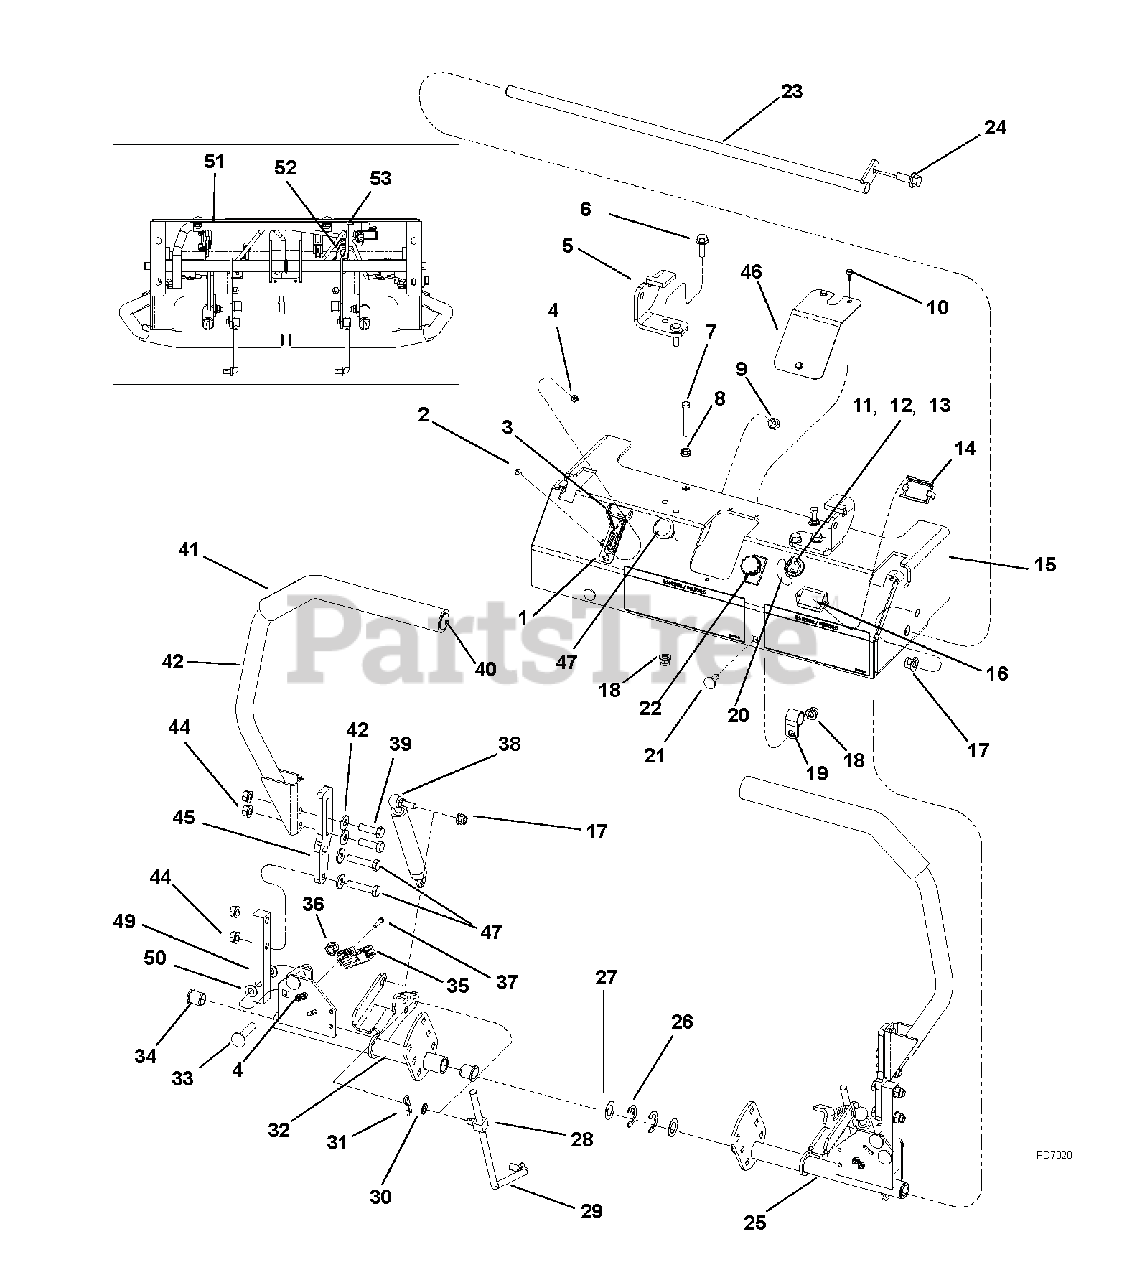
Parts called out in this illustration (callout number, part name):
1	DECAL, CONSOLE
2	SCREW,.164X.500 ZN RD HD MACH
3	CABLE, THROTLE 56.5"
4	#8.32 ELASTIC STOP NUT
5	BRACKET, LH, SEAT PLATE
5	BRACKET, RH, SEAT PLATE
6	SCREW,HEX,FL,JDS123,M8X1.25X25
7	CAP SCREW, HEX HEAD
8	SPINLOCK NUT - 1/4
9	NUT, .375 UNF2B HEX JDS14 8 ZN
10	@SCR-TAP 10-24X.50 HWH TR YWZC
11	KEY, IGNITION A880
12	NUT, KNURLED
13	SWITCH, IGNITION KEY
14	CLIP, ZTRAK HOURMETER RETAININ
15	PLATE, CONSOLE GDANE
16	METER, HOUR - LCD
17	LOCKNUT,FL,ISO7043,M10X1.5-10-
18	LOCKNUT, M8X1.25 NYLOC FLG 10Y
19	P-CLIP, .750 INSULATED
20	LABEL, IGNITION KEY
21	BOLT, M8X1.25X20 CRG 8.8 Y
22	SWITCH, PTO (PULL/PUSH)
23	PIVOT,CONTROL SHAFT-PLATED
24	SCREW,HEX,FL,JDS123,M10X1.5X25
25	WLDT, PIVOT CONTROL LH BLCK
26	RING, RETAINING
27	WASHER, .627X1.09X.030 THST Y
28	SWIVEL, 3/8-24
29	ROD, CONTROL
30	SHIM, CIRCULAR
31	PIN, HAR .094X1.53 5/16-1/2 Y
32	WLDT, PIVOT CONTROL RH BLCK
33	BOLT,RH,SQNECK,JDS137,M10X1.5X
34	BUSHING, NYLON
35	SWITCH, PLUNGER DP - N.O.-N.C.
36	LOCKNUT, M10X1.50 NYLOC Y
37	SCREW, 8-32X .75 PAN PHL Y
38	ABSORBER, ASM. WITH BALL STUD
39	BOLT, 3/8-16X1.25 HEX 5 Y
40	PLUG, 7/8" END
41	FOAM GRIP
42	WLDT, CONTROL LEVER PAINTED
43	WASHER, .313 REG FLAT Y
44	LOCKNUT, 3/8-16 WHIZ Y
45	PLATE, HANDLE HEIGHT
46	COVER, CONSOLE
47	CABLE, CHOKE57.0"
48	BOLT, 3/8-16X1.75 HEX 5 Y
49	ARM, CONTROL CONSOLE
50	WSHR-FL-NY .375X.75X.060
51	WIRING HARNESS
52	WASHER,M21X37X3 DIN125T2 300HV
53	CABLE TIE, .31 X 14.6 - BLACK
